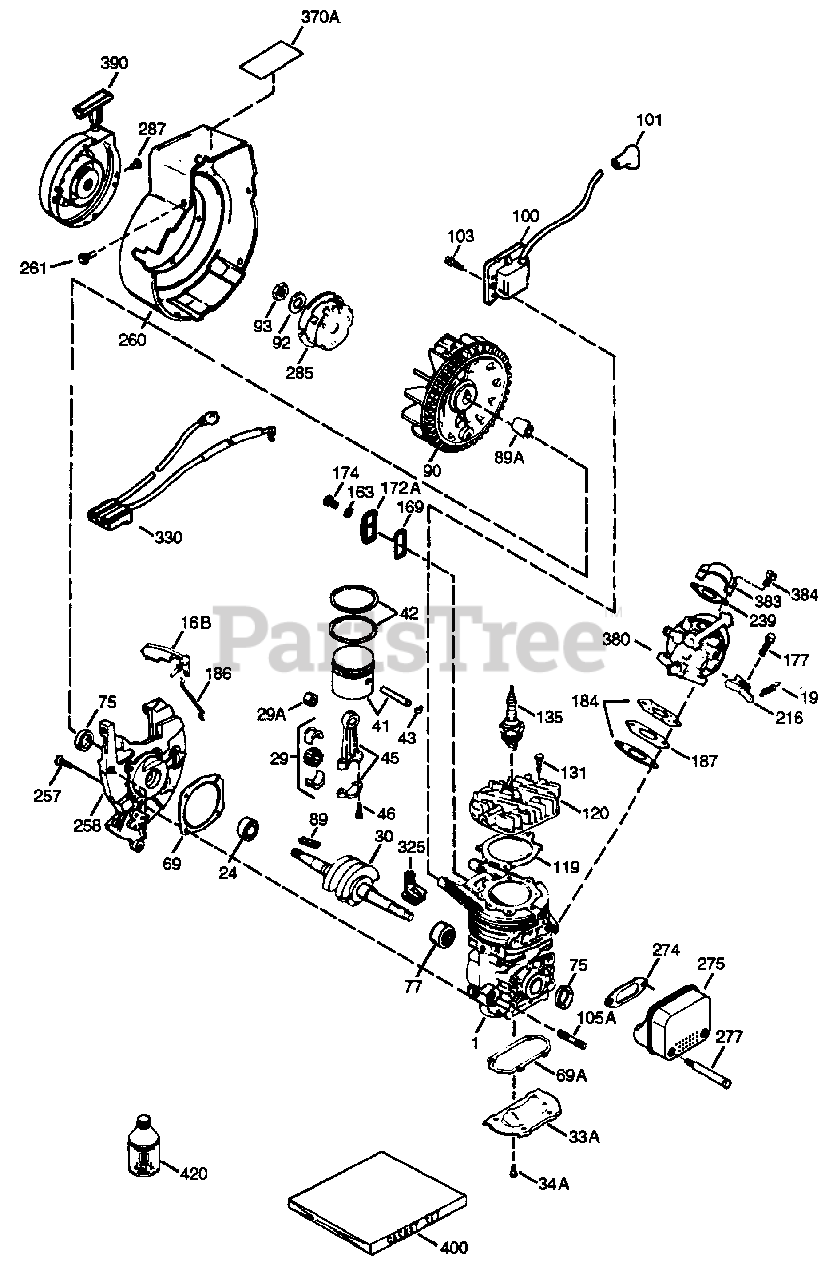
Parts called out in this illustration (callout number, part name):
1	Cylinder (Order Short Block if Replacement is needed)
16B	Air Vane
19	Extension Spring
24	Ball Bearing
29	Needle Bearing & Liner Set (37 Needles)
29A	Cartridge Bearing
30	Crankshaft
33A	Cover Plate
34A	Screw, Torx T-25
41	Piston & Pin Assembly
42	Ring Set
43	Piston Pin Retaining Ring
45	Connecting Rod Assembly (Incl. Ref. #29, 29A, & 46)
46	Connecting Rod Bolt
69	Cylinder Cover Gasket
69A	Cover Plate Gasket
75	Oil Seal
77	Cartridge Bearing
89A	Adapter Sleeve
90	Flywheel
92	Belleville Washer
93	Flywheel Nutt
100	Solid State Ignition (Incl. Ref. #101)
101	Spark Plug Cover
103	Screw, Torx T-15
119	Cylinder Head Gasket
120	Cylinder Head
131	Screw, Torx T-30
135	Resistor Spark Plug
169	Cover Plate Gasket
172A	Compression Release Cover
174	Screw, Torx T-25
184	Carburetor Gasket
186	Governor Link
216	R.P.M. Adjusting Lever
239	Air Cleaner Gasket
257	Screw, Torx T-30
258	Blower Housing Base (Incl. Ref. #27)
260	Blower Housing
274	Exhaust Gasket
275	Muffler (Incl. Ref. #274 & 277)
285	Starter Cup
325	Wire Clip
330	Wire Harness
370A	Instruction Decal
380	Carburetor (Incl. Ref. #184)
383	Spit Cup
384	Screw, Torx T-25
390	Rewind Starter
400	Gasket Set
420	2-Cycle Oil (8 oz.)
